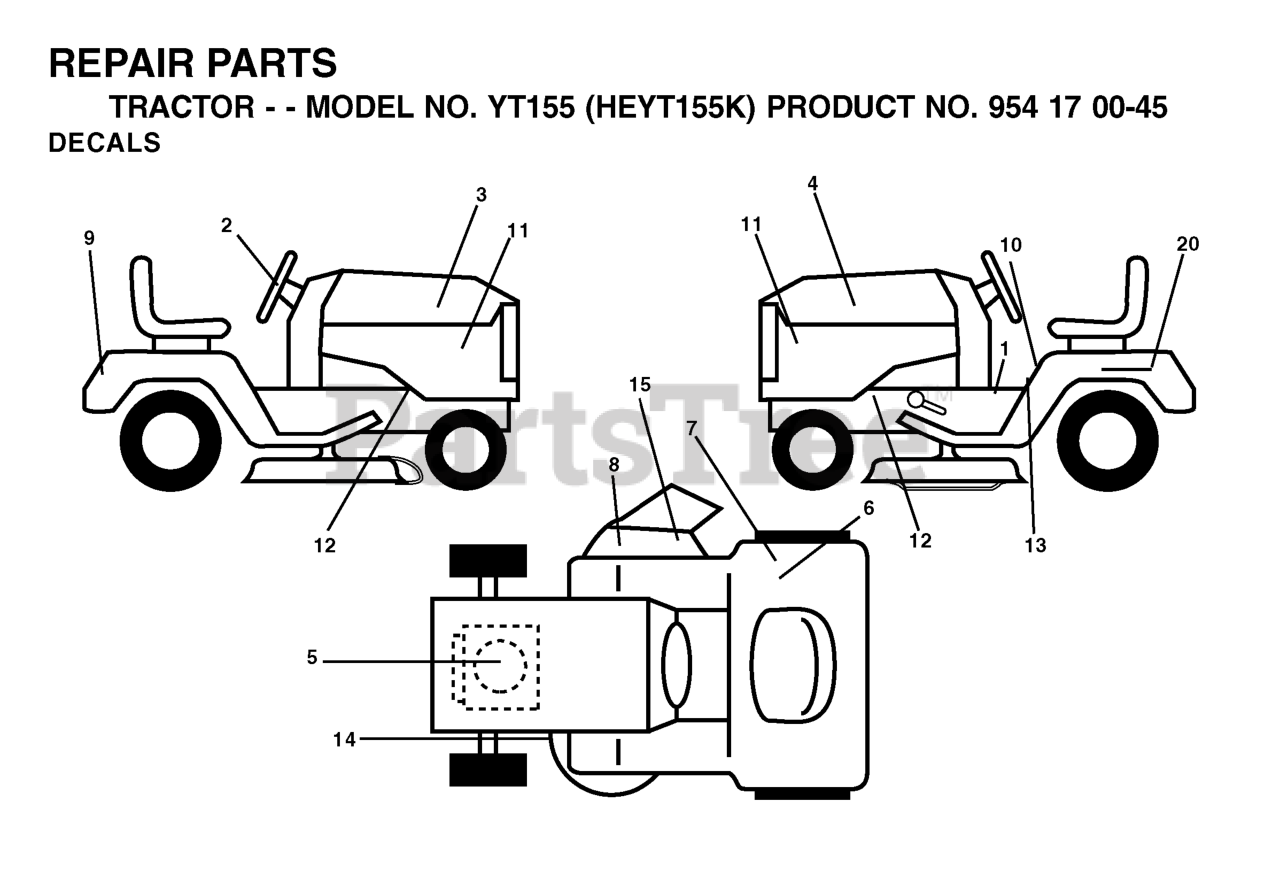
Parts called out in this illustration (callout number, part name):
1	DECAL PARK BRAKE
2	DECAL.WHEEL.STEERING.HUSQ.PERM
6	DECAL CERTIFICATION
7	DECAL EUROPE STANDARD CE
8	DECAL MOWER CUT/FINGER
9	DECAL FENDER HUSQ
10	DECAL READ OWNER'S MAN SYMS
11	DECAL PNL SIDE
13	DECAL
14	DECAL V BELT SCHEMATIC
15	DECAL DECK "B" 42"
20	DECAL BTRY SYMBOLS
